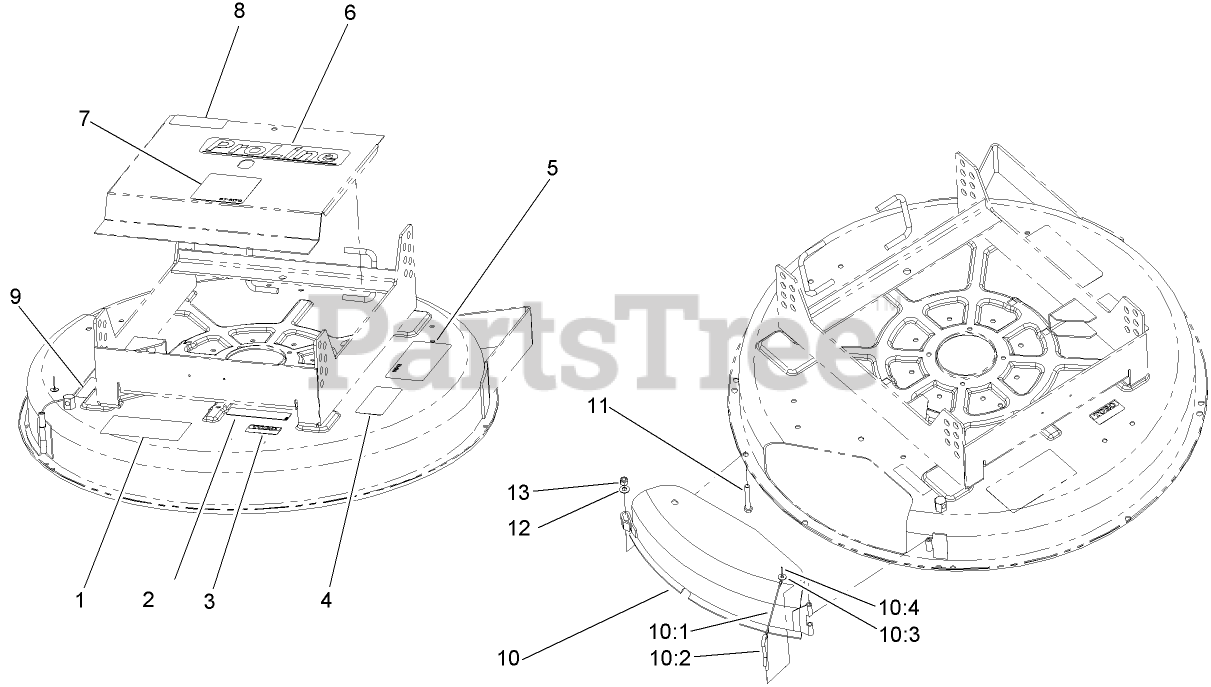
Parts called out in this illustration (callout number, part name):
1	DECAL-DANGER, THROWN OBJECT
2	DECAL-DANGER
3	DECAL-STD, SAFETY
4	DECAL-TORQUE
5	DECAL-HOC
7	DECAL
8	DECAL-HOT
9	DECAL-DANGER
10	MULCHER COVER ASM
10:1	LANYARD
10:2	PIN-LOCKING, CHUTE
10:3	WASHER-PLAIN
10:4	RIVET-BLIND
11	SCREW-HH
12	WASHER-PLAIN
13	NUT-LOCK, NI
